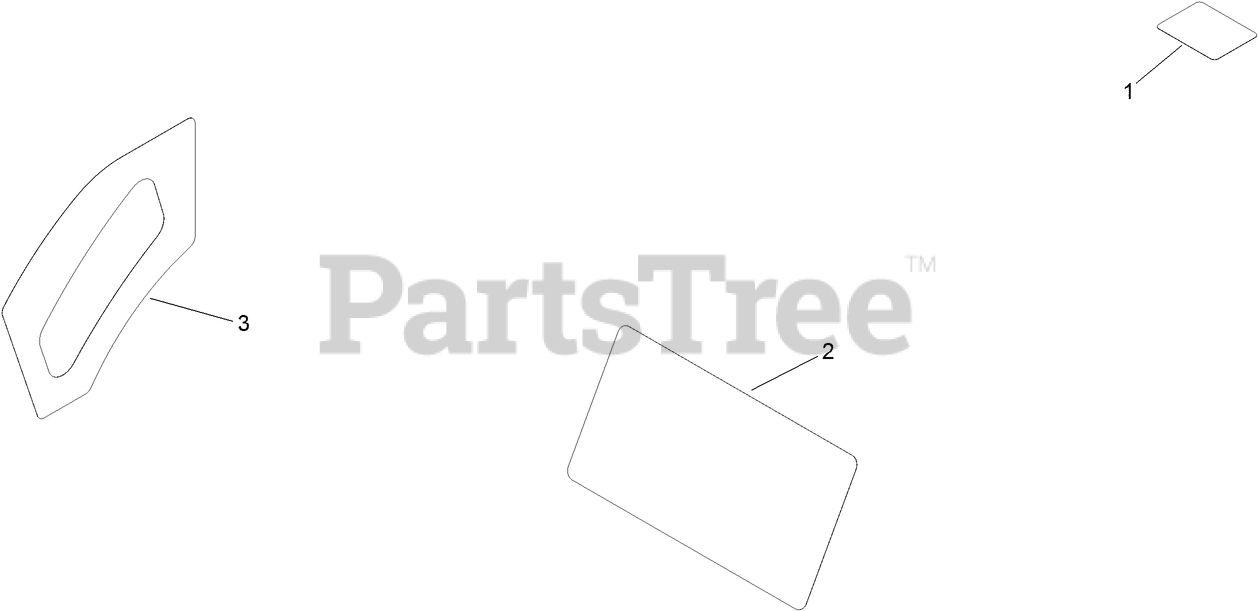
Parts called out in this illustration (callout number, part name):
1	DECAL-MAINTENANCE
2	DECAL-CONTROL, SPEED
3	DECAL-HOC
